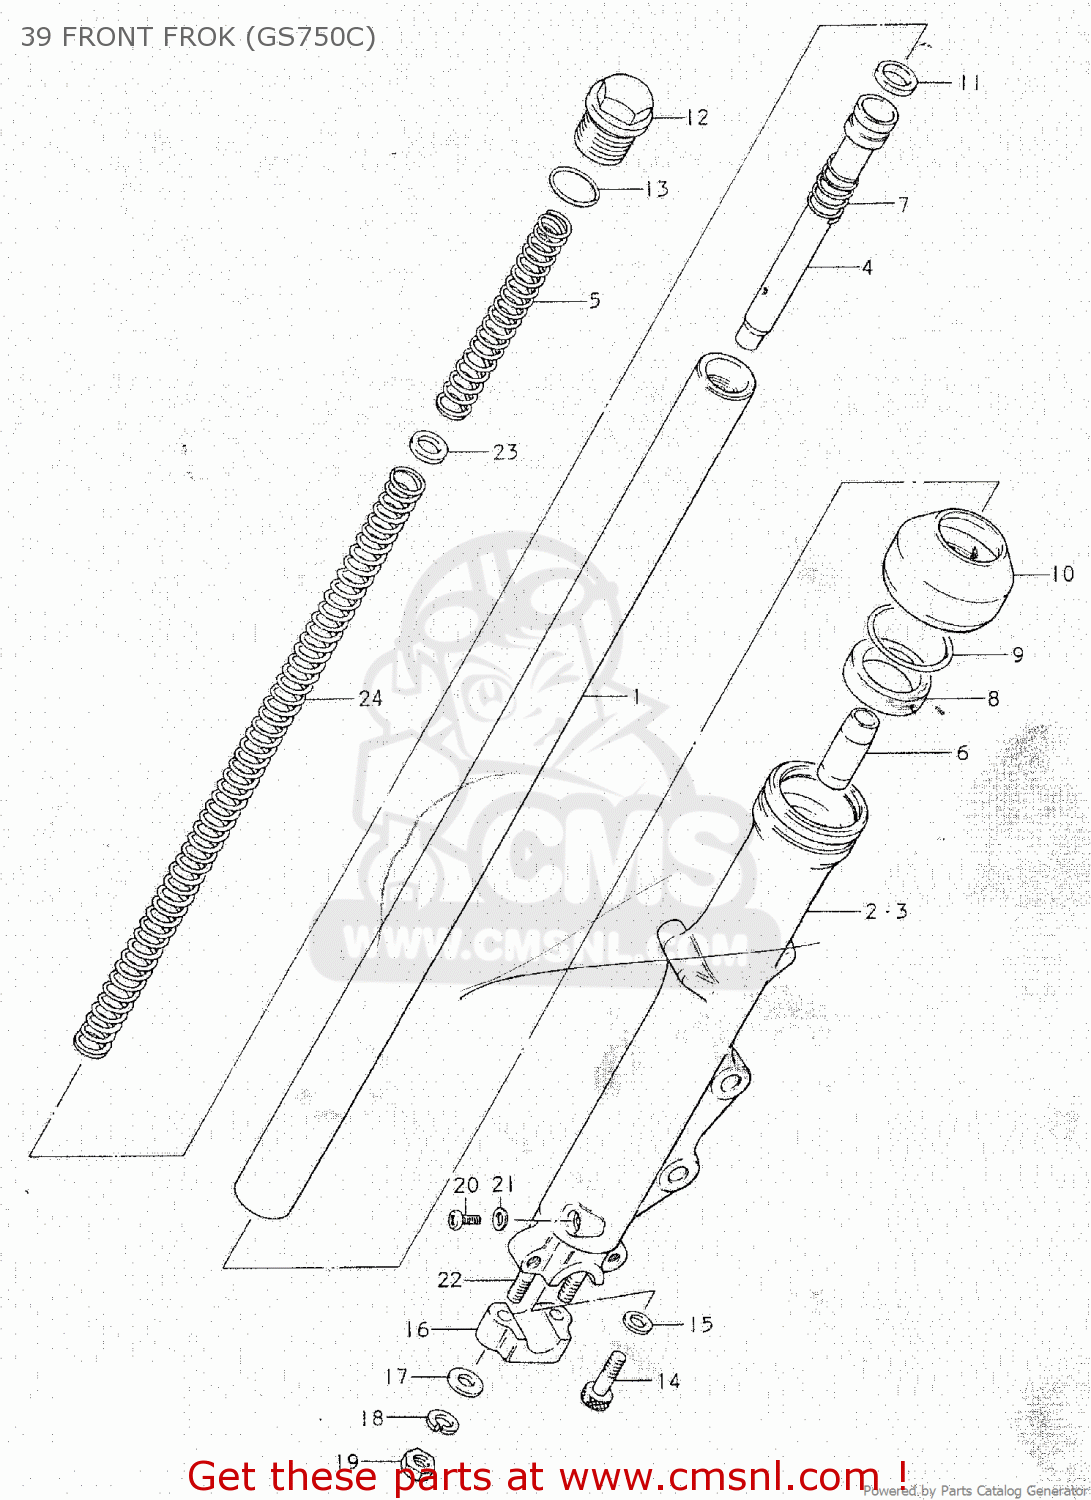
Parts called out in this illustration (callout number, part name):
1	TUBE,INNER
2	TUBE,FORK,LEFT,OUTER
3	TUBE,FORK,OUTER,RIGHT
4	CYLINDER,FRONT FORK
5	SPRING,FRONT FORK,UPPER
6	PIECE,OIL LOCK
7	SPRING,FORK REBOUND
8	OIL SEAL,FRONT FORK
9	RING,OIL SEAL STOPPER
10	BOOT
11	RING
12	CAP,INNER TUBE
13	O RING
14	BOLT
15	GASKET (NAS)
16	HOLDER,AXLE
17	WASHER
18	LOCK WASHER
19	NUT
20	SCREW
21	GASKET (NAS)
22	STUD 8X25
23	WASHER
24	SPRING,FRONT FORK
